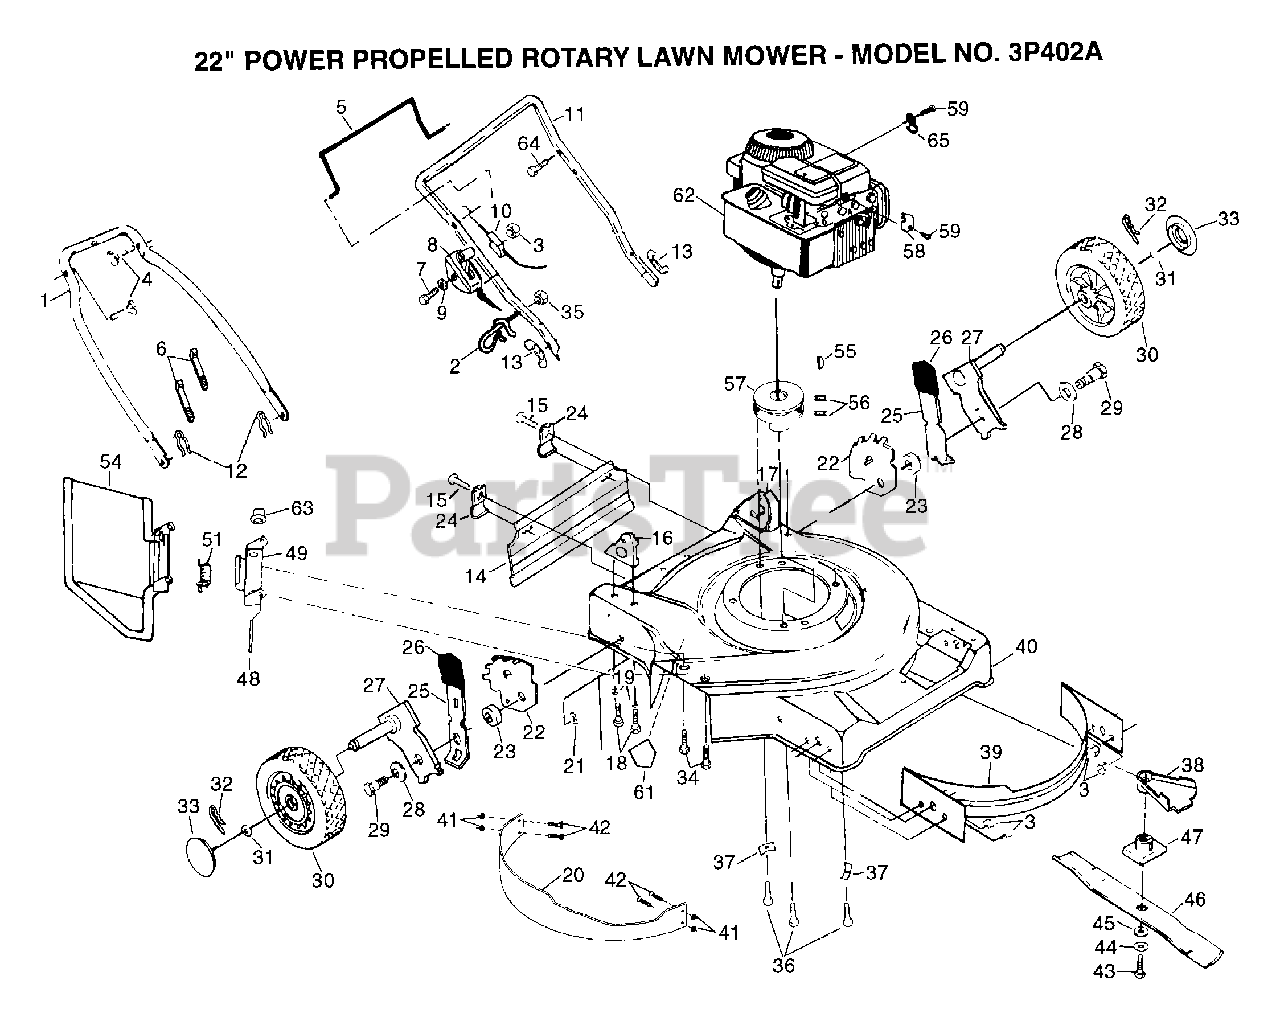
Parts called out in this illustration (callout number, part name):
2	ROPE GUIDE
4	BOLT.HANDLE.LM
5	CONTROL BAR
8	CONTROL THROTTLE
9	WASHER PM
10	"CABLE,ENG ZONE CO"
12	HAIRPIN COTTER
13	"NUT,WING PM"
15	TAPPING SCREW
18	SCREW
19	STEEL WASHER
20	BAFFLE.MULCH.22SD
21	LOCKNUT PM
22	BRACKET.ADJ.9POS.
24	"BRKT,DEFL PM"
25	SPRING SELECTOR
26	KNOB PM
27	AXLE ARM
28	"WASHER, BELLEVIL."
31	WASHER
32	RETAINER CLIP PM
33	HUB CAP
34	SCREW
35	NUT
36	SCREW
39	BAFFLE FRONT 22SD
40	KIT.HSG.22SD.FWGD
41	LOCKNUT
43	SCREW
44	LOCKWASHER
45	"WASHER,HARDEN"
47	ADAPTOR.BLADE.LM
48	"ROD,HINGE "
49	"BRKT,HSG"
51	"SPRING,TORSION"
55	HI PRO KEY PM
56	SCREW
57	ENGINE.PULLEY.FWG
58	CABLE CLAMP
59	SCREW PM
61	DECAL HYT
63	PUSH ON SPEED NUT
64	"SCREW,PAN HD"
65	GUIDE CLIP PM
